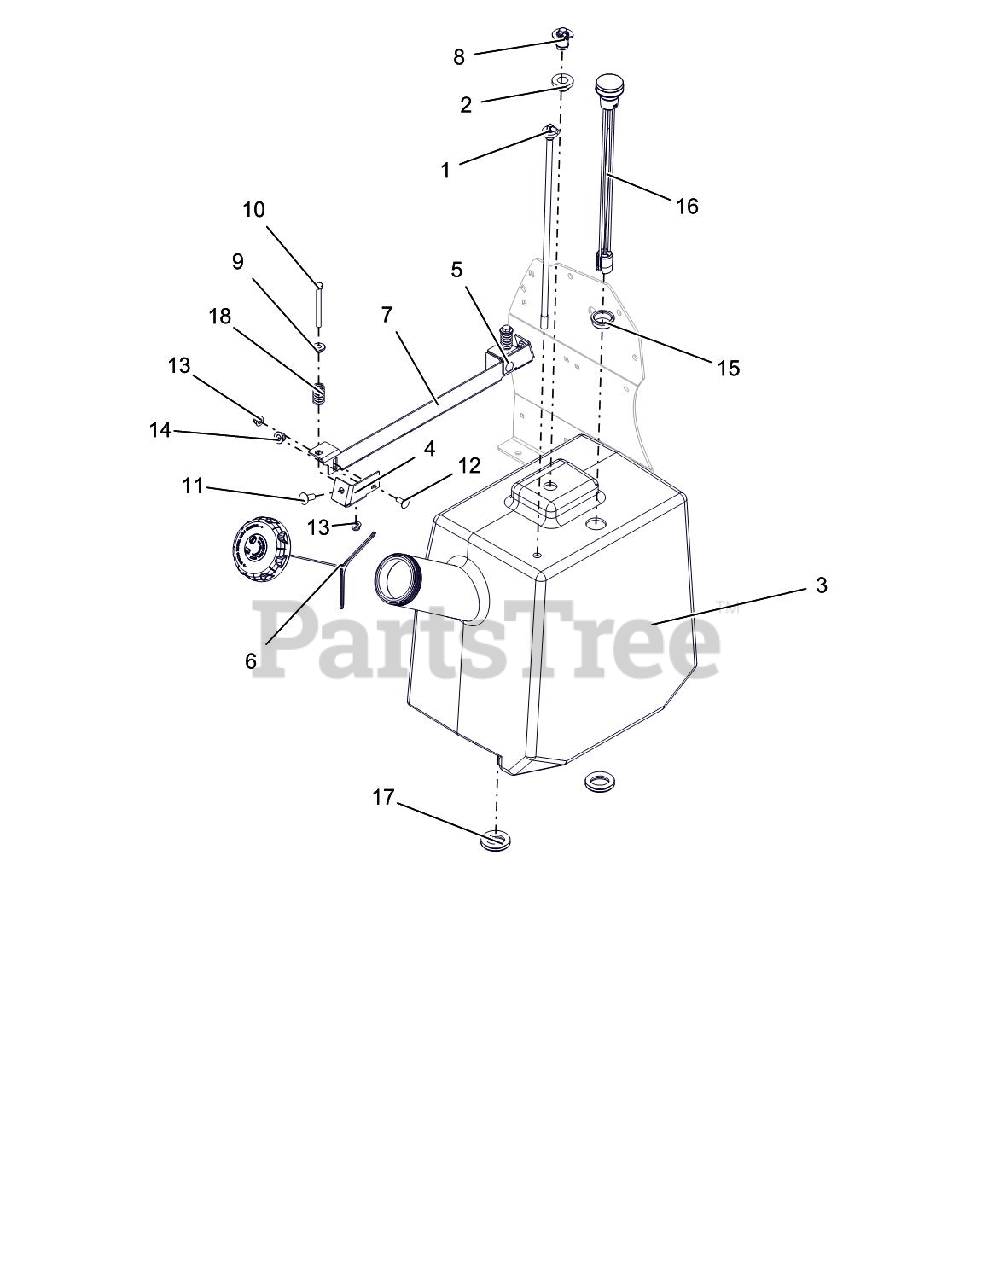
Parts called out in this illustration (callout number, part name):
1	ASM, FUEL LINE,PRO-STANCE
2	GROMMET, REMOTE VENT NITRILE
3	TANK,EPA FUEL,PRO-STANCE
4	WLDMT, TANK HOLDDOWN MOUNT-RH (BLACK)
5	WLDMT, TANK HOLDDOWN-LH (BLACK)
6	CAP, FUEL VENT-IN AUTOLOCK
7	HOLDDOWN, FUEL TANK
8	VALVE, 2-WAY
9	BSHG, FLG .32X.500.344X.880
10	BLT-HEX .31-18X3.25 GR5 YWZC
11	BLT-RDHDSHSQNK.38-16X1.0 G5YZ
12	BLT-RDHDSQNK .31-18X.75 G5 YWZC
13	NUT-LK-NYL-FLG .31-18 YWZC
14	NUT-LK-NYL-FLG .38-16 YWZC
15	GROMMET, FUEL GAUGE
16	GAGE, REMOTE FUEL SEALED 15"
17	GROMMET, 1.25"
18	SPRG, COMPRESSION
